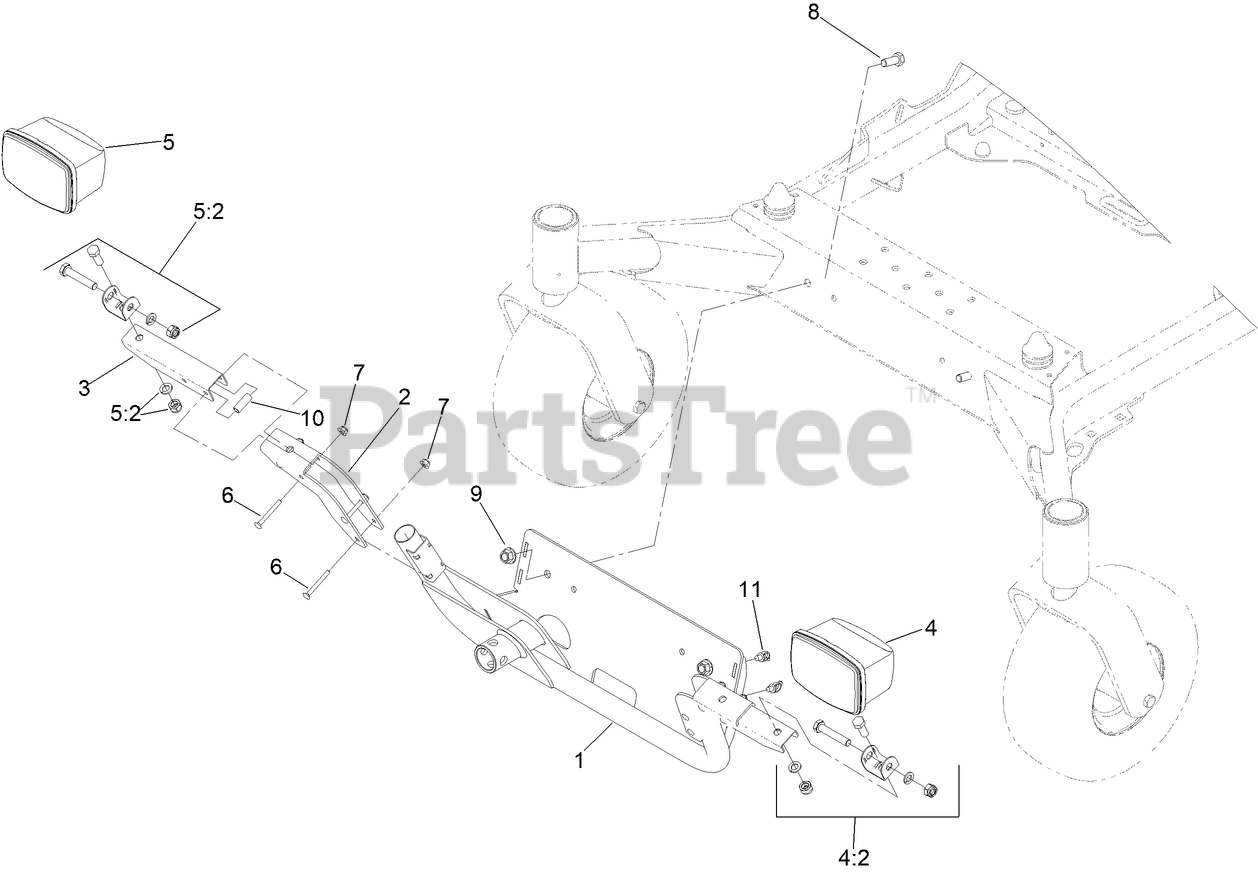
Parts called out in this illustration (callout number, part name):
1	MOUNT-LIGHTS [BLACK]
2	MOUNT-LIGHT
3	MOUNT-EXTENSION
4	LH LIGHT ASM
4:2	LIGHT MOUNT KIT
5	RH LIGHT ASM
5:2	LIGHT MOUNT KIT
6	SCREW-CARR
7	NUT-HF
8	SCREW-HH
9	NUT-LOCK
10	SPACER, LIGHT MOUNT
11	CLIP-TIE
